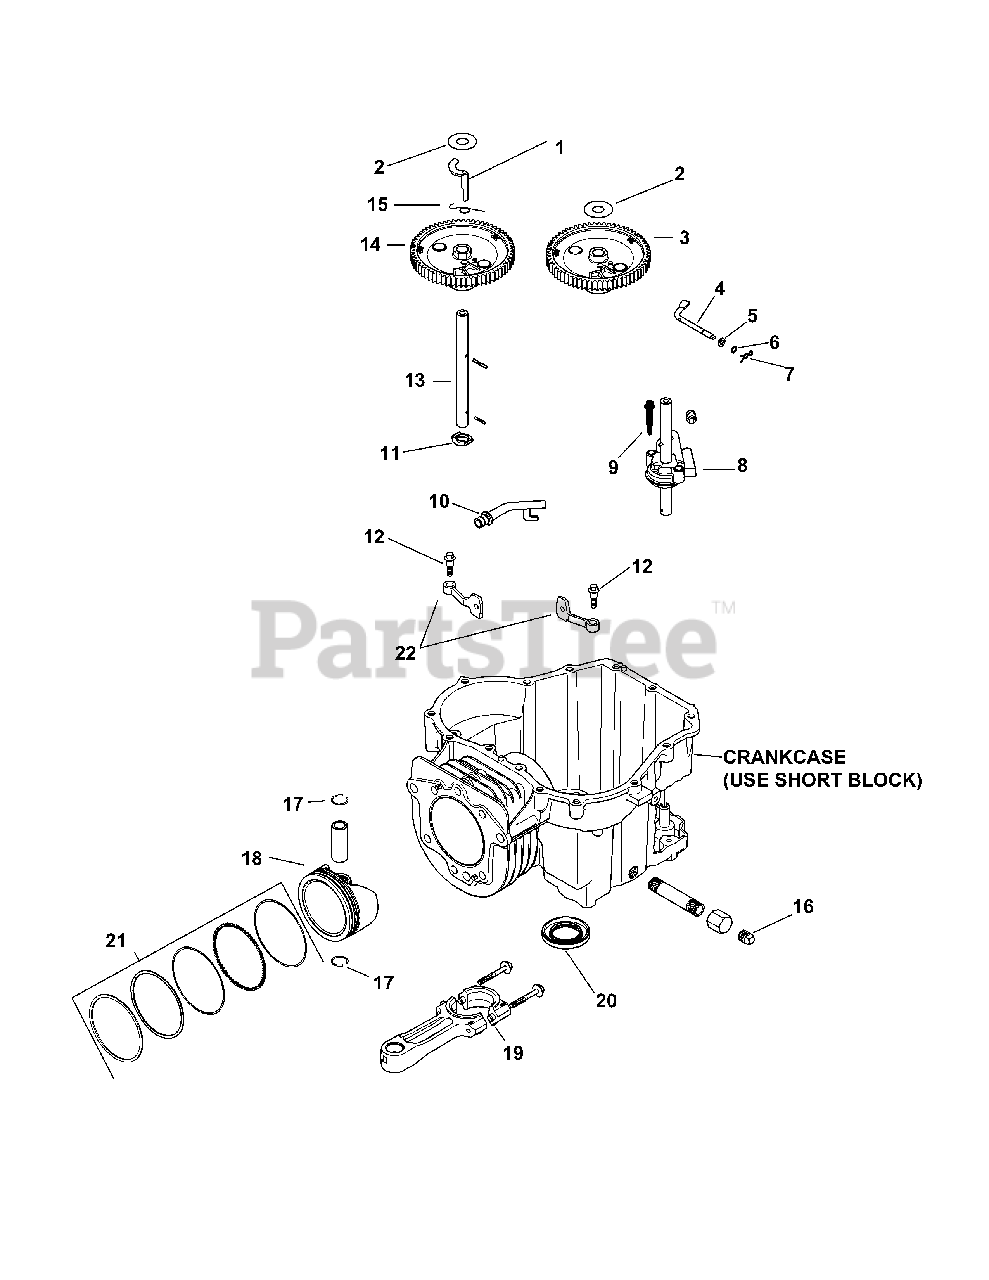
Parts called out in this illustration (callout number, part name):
2	Thrust -Acr. Washer
3	Cam Gear Assembly, Intake
4	Governor Cross Shaft
5	Flat Washer, 6 Mm
6	Flat Washer, 1/4
7	Hitch Pin Clip
8	Oil Pump Ass’y Kit
9	Oil Pump Screw
10	Drainback Tube
11	Thrust Washer
12	Shd. Thd. Frm. Screw, M6 X 1 X 26
13	Cam Center Shaft Kit
14	Cam Gear Assembly
16	Square Head Pipe Plug, 3/8
17	Piston Pin Retainer
18	Piston w/ Ring Set, 94mm
19	Connecting Assembly Rod
21	Ring Set (94mm)
22	Cam Lever Kit
